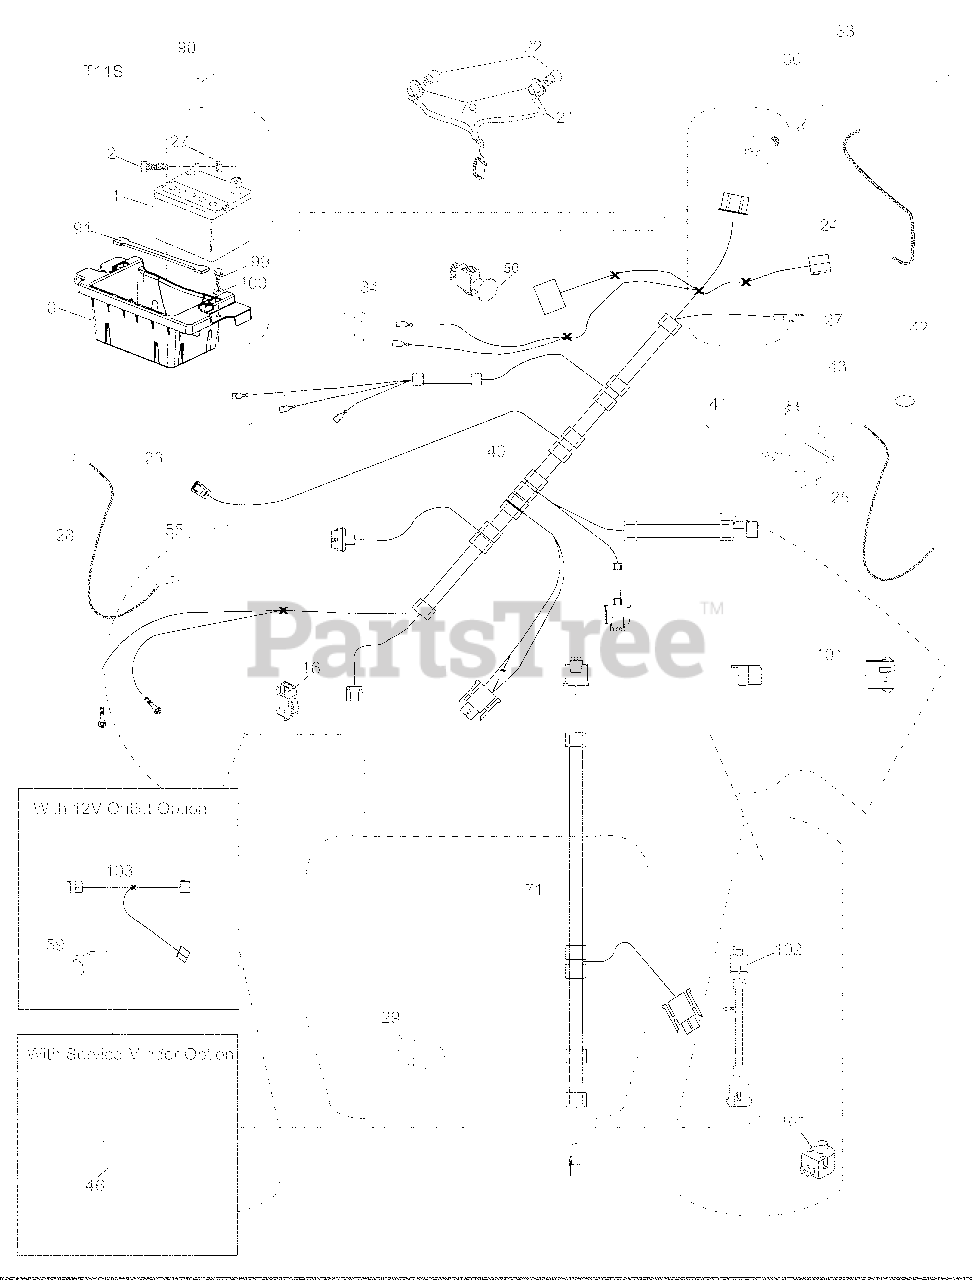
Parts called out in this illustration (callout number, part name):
1	Battery
2	Bolt Hex Hd 1/4-20 unc x 3/4
8	Battery Box
16	Switch Interlock
21	Harness Socket Light
22	Bulb, Light #1156
24	Cable Battery
25	Cable Starter
27	Nut Keps Hex 1/4-20 unc
28	Cable Ground 21 Blk 6 Ga."
29	Switch Seat
30	Switch Ign
33	Key/Chain
34	Switch Light/Reset
40	Harness Ign. Dash
41	Screw Thd Cut 1/4-20 x 1/2
42	Cover Terminal Red
43	Solenoid
46	Gauge Hourmeter
50	Switch PTO
55	Screw Thdrol 5/16-18 x 3/4
71	Harness Ign
79	Socket Asm Bulb Twistlock
90	Cover Terminal Battery
91	Strap Battery
99	Screw Hexwsh Thdrol 1/4-20 x 3/4
100	Washer 9/32 x 7/8 x 16 Ga.
101	Pigtail Harness Clutch
102	Harness Pigtail
105	Switch Reverse TT Pedal Control
